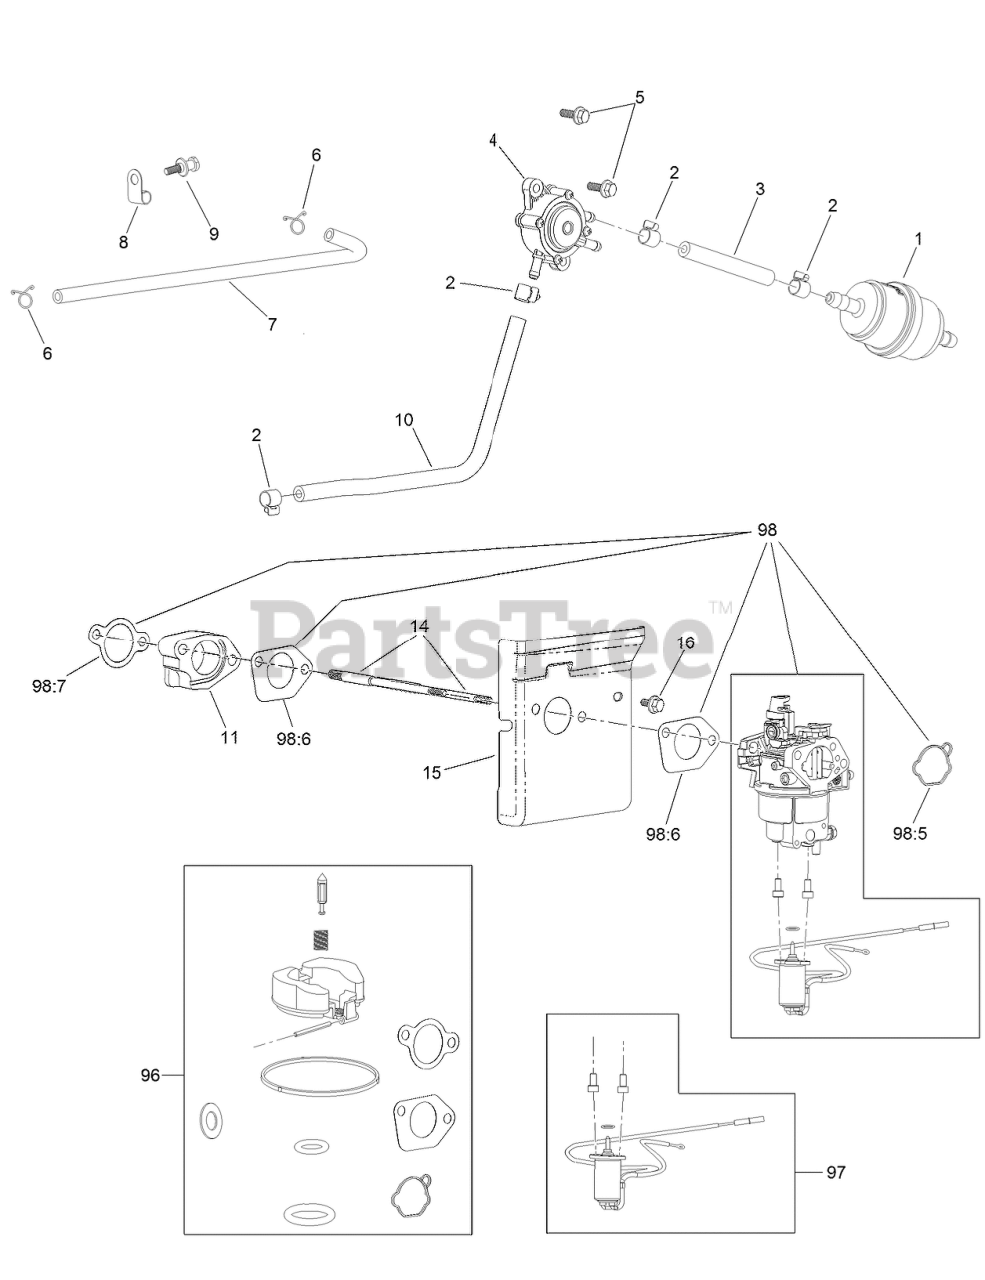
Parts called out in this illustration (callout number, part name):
1	FILTER-FUEL
2	CLAMP-FUEL LINE
3	LINE-FUEL
4	PUMP-PULSE, FUEL
5	SCREW-HHF
6	CLAMP-HOSE
7	LINE-PULSE
8	CLAMP-J
9	SCREW-SHOULDER, HH
10	LINE-FUEL
11	INSULATOR-CARBURETOR
14	STUD-MOUNT, CARBURETOR
15	SHIELD-HEAT
16	SCREW-HHF
96	CARB REPAIR KIT WITH GASKETS
97	SOLENOID KIT
98	CARBURETOR KIT
98:5	GASKET-CARBURETOR
98:6	GASKET-CARBURETOR
98:7	GASKET-CARBURETOR
